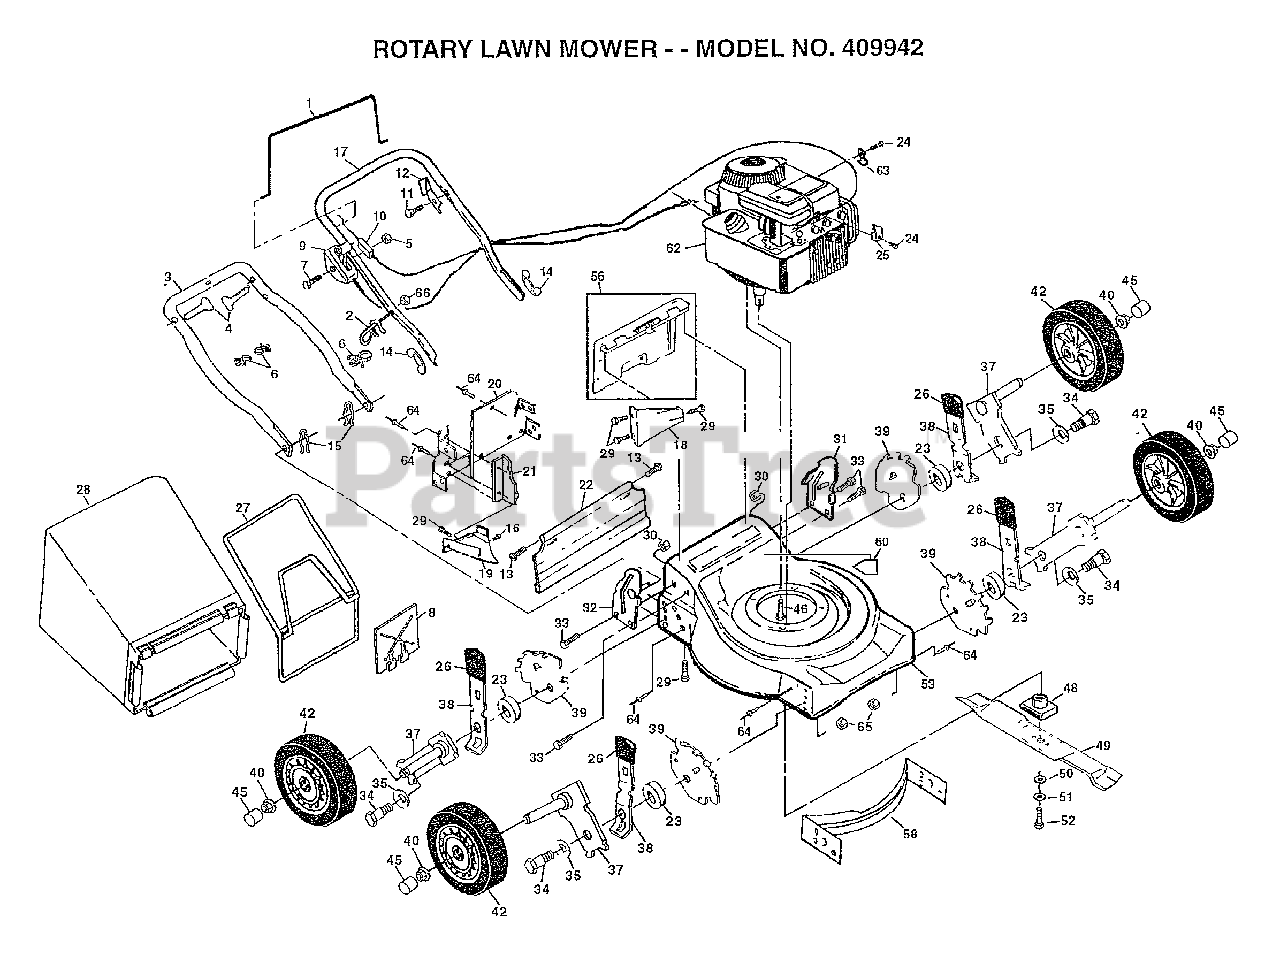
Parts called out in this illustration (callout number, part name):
1	CONTROL BAR PM
2	ROPE GUIDE
4	BOLT.HANDLE.LM
7	SCREW.HXHD.WASH.
8	MULCHER PLATE
9	CONTROL THROTTLE
10	"CABLE,ENG ZONE CO"
11	TAPPING SCREW
12	"BRKT,UPSTOP"
13	HINGE SCREW
14	"NUT,WING PM"
15	HAIRPIN COTTER
16	SCREW.HXTAP.10-24
18	REAR BAFFLE
19	DISCHARGE GUARD
20	PLATE.BACK.20RD
22	SKIRT.PUSH.20RD
23	SPACER.HEIGHT.ADJ
24	SCREW PM
25	CABLE CLAMP
26	KNOB PM
27	FRAME.CATCHER.2.5
28	GRASSBAG.250B1.BL
29	SCREW
31	BRACKET.HDL.LH.
32	BRACKET.HDL.RH.
33	SCREW.HXWS.5/16
34	BOLT.SHLD.W/PATCH
35	"WASHER, BELLEVIL."
37	ARM.AXLE.ASM.BZP.
38	SPRING SELECTOR
39	BRACKET.ADJ.9POS.
40	HEX FLANGE LOCKNT
45	HUB CAP-PLASTIC
46	BOLT.ENG.3/8-16
48	BLADE ADAPTOR
49	BLADE.20.MULCH.AY
50	"WASHER,HARDEN"
51	LOCKWASHER
52	SCREW
53	HOUSING ASSY
56	KIT.DOOR.RR.20STL
60	DECAL DANGER E/S
63	GUIDE CLIP PM
64	BLIND RIVET
66	NUT
